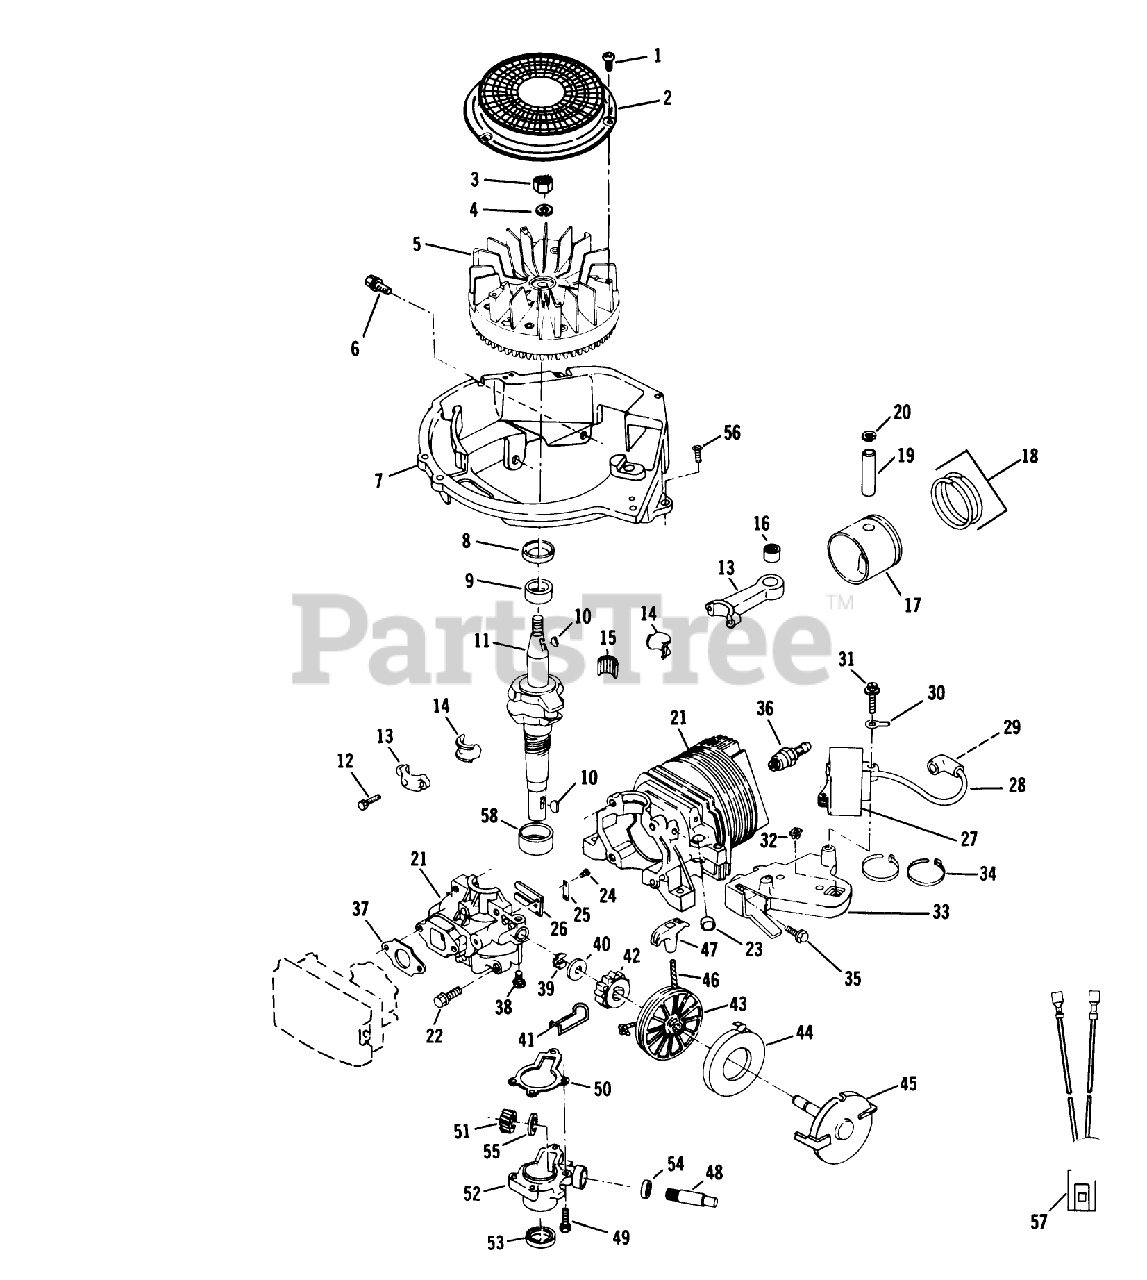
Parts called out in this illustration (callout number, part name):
1	SCREW F
3	NUT
6	SCREW-SEMS
9	BEARING V
10	KEY
12	SCREW-HSH
14	LINER ASM
16	BEARING AY F
20	RING-RETAINING
22	SCREW S
23	PLUG-CORE VF
25	PLATE-BACKUP, REED
28	HT LEAD&COVER XEV
30	TERMINAL S
32	NUT-CLIP
33	BRACKET S
37	GASKET CARB S
40	WASHER S
43	PULLEY STARTER S
44	SPRING&RET.AY S
45	SPRING CUP&PIN S
47	HANDLE STARTER S
50	GASKET S
51	GEAR, DR SHAFT S
53	SEAL-OIL
54	SEAL S
55	THRUST WASHER
56	SCREW F
58	BEARING S
